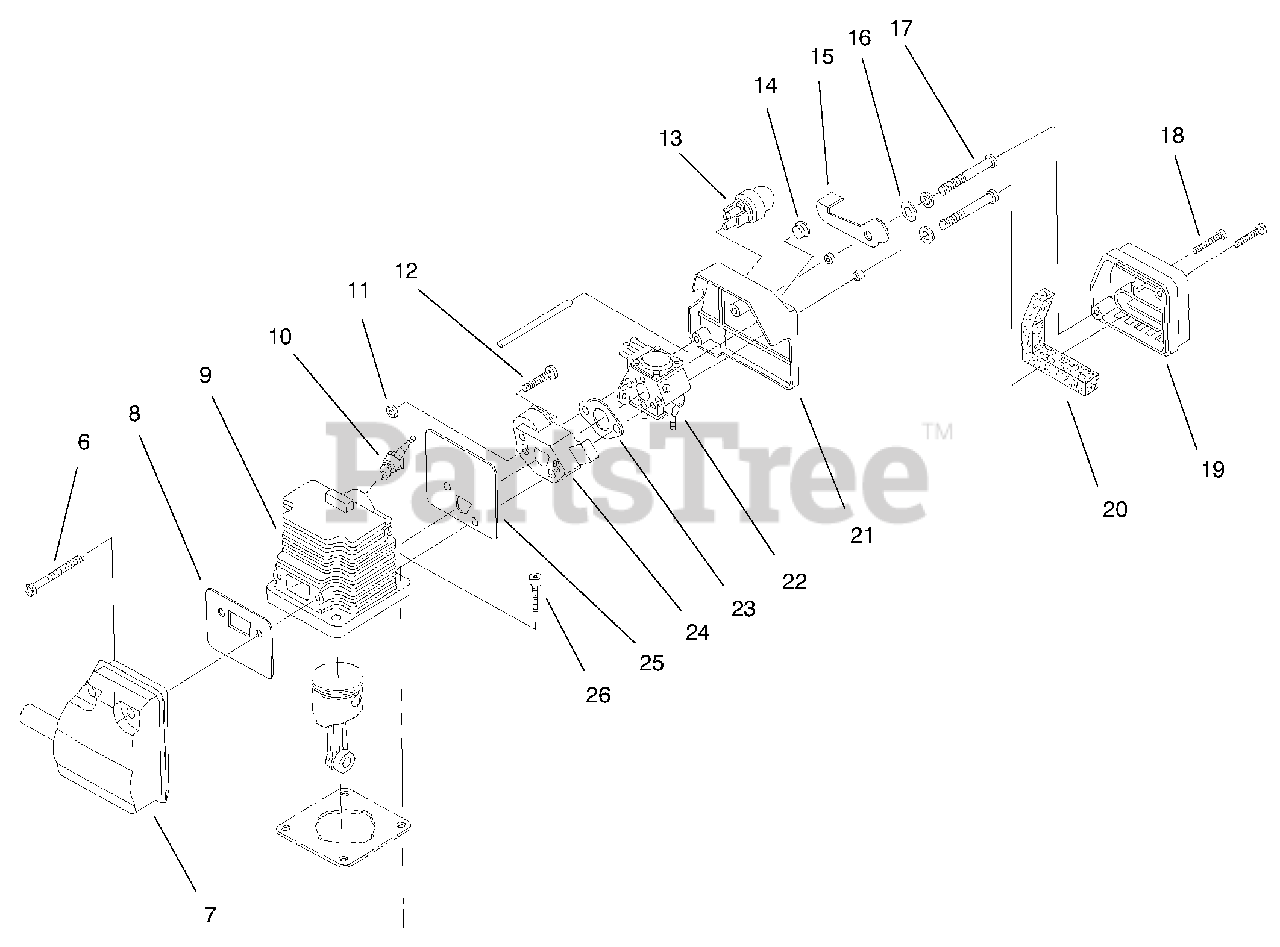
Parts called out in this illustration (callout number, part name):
6	Muffler Mounting Screws
7	Muffler Asm.
8	Muffler Gasket
9	Cylinder
10	Spark Plug
11	Spacer Nut Set
12	Spacer Screw Set
13	Primer Bulb & Hose
14	Plug Switch
15	Choke Lever
16	Wavey Washer
17	Carburetor Mount Screw Asm.
18	Screw
19	Air Cleaner Cover
20	Air Filter Element
21	Air Cleaner Base Asm.
22	Carburetor Asm.
23	Carburetor Gasket
24	Spacer, Carburetor Asm.
25	Cylinder/Carburetor Gasket
